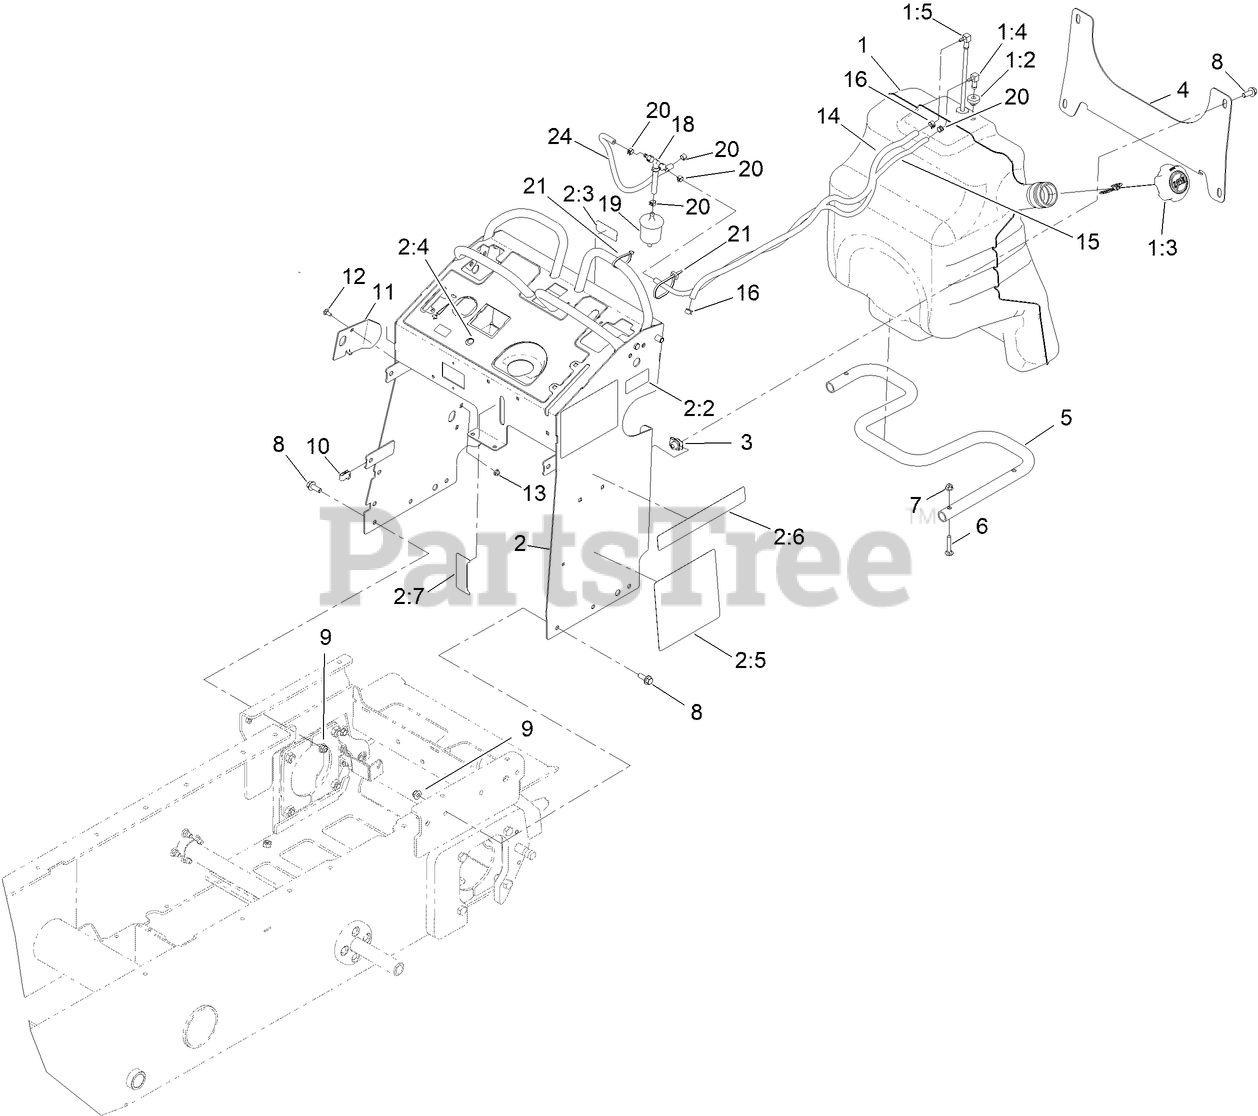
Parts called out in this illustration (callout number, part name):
1	FUEL TANK ASM
1:2	BUSHING
1:3	CAP-FUEL
1:4	FITTING-ELBOW, 90 DEG
1:5	FUEL TUBE ASM
2	TOWER ASM
2:2	DECAL-FILL, FUEL
2:3	DECAL-FUSE
2:4	DECAL-CONTROL PANEL
2:5	DECAL-SERVICE
2:7	DECAL-LEVEL, OIL
3	NUT-TINNERMAN
4	BRACKET-CROSS
5	TUBE-MOUNT, FUEL TANK
6	BOLT-CAR
7	NUT-HF, NI
8	SCREW-HHF
9	NUT-HF, NI
10	NUT-CLIP, U
11	PLATE-STRIKER
12	SCREW-CARR
13	NUT-HF
14	HOSE-FUEL
15	HOSE-FUEL
16	CLAMP-HOSE
18	TEE AND CHECK
19	FILTER-FUEL
20	CLAMP-HOSE
21	TIE-CABLE
24	HOSE-VENT
